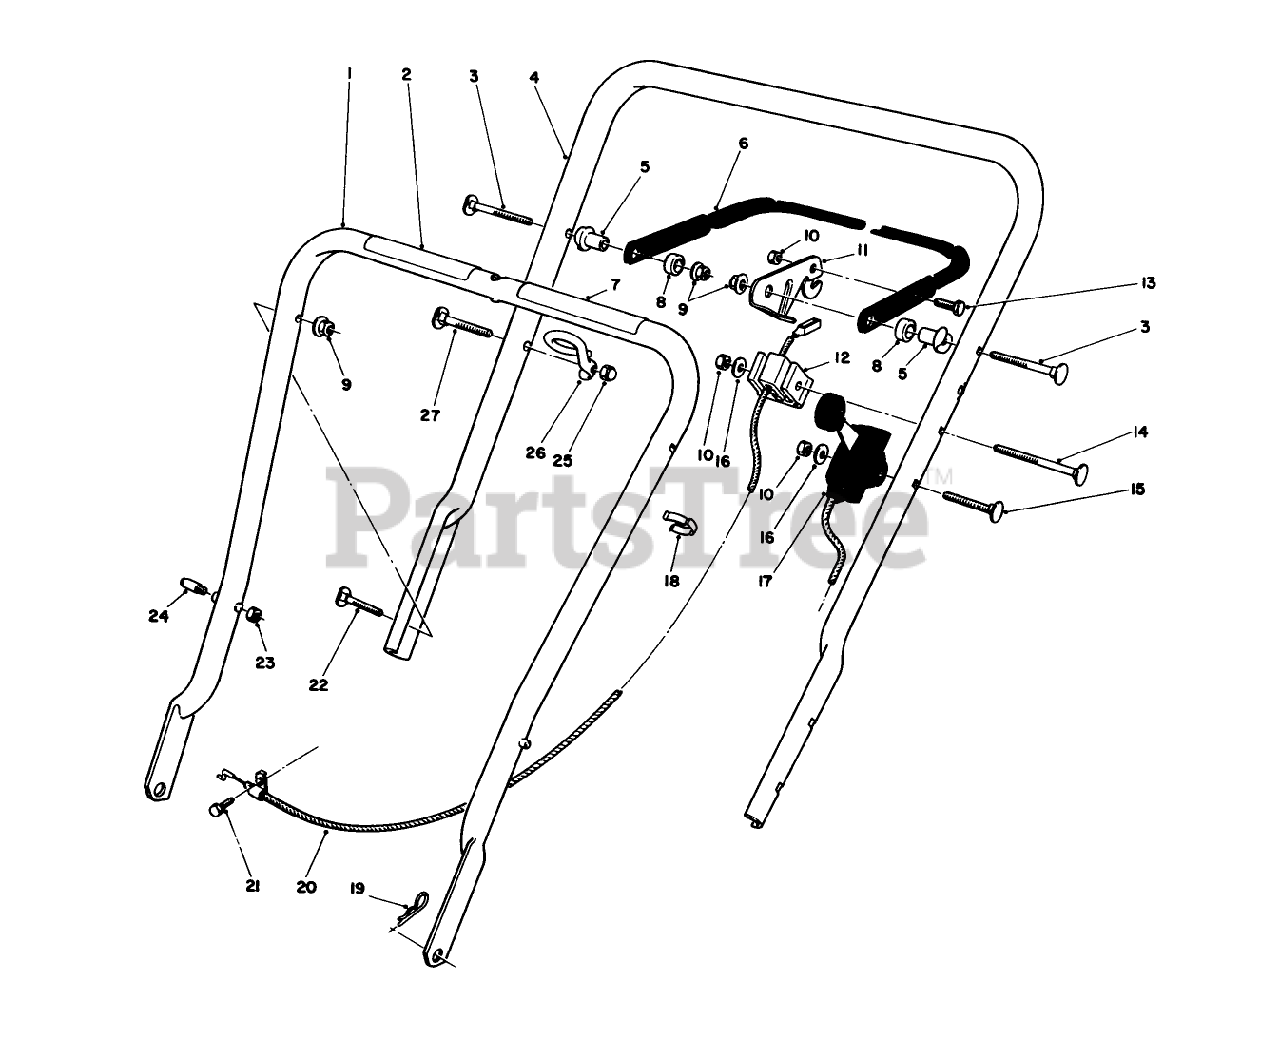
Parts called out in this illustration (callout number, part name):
5	SPACER-SUPPORT
8	SPACER-NYLON
9	NUT-LOCK, NI
10	NUT-LOCK, NI
12	SUPPORT-CABLE
13	SCREW-HH
14	HANDLE SCREW
15	SCREW-HANDLE
16	WASHER-FLAT
17	SERVICE THROTTLE CONTRO
18	BOWDEN CLIP
19	PIN-COTTER, HAIR
23	NUT-LOCK, NI
24	HANDLE PIN
25	NUT-CAP
27	HANDLE SCREW
